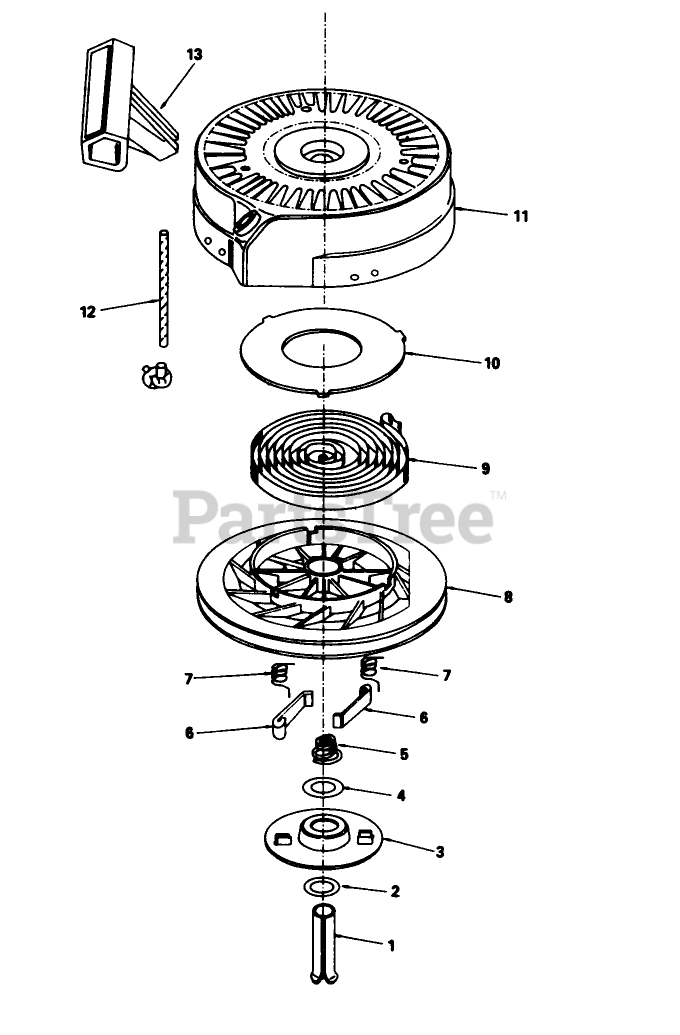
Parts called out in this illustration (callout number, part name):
1	Pin Spring
2	Washer
3	Retainer
4	Washer
5	Brake Spring
6	Dog-Starter
7	Spring-Dog
8	Pulley
9	Rewind Spring
10	Cover-Spring
11	Housing-Starter
12	Rope-Starter (98 cut to length)
13	Handle-Starter
